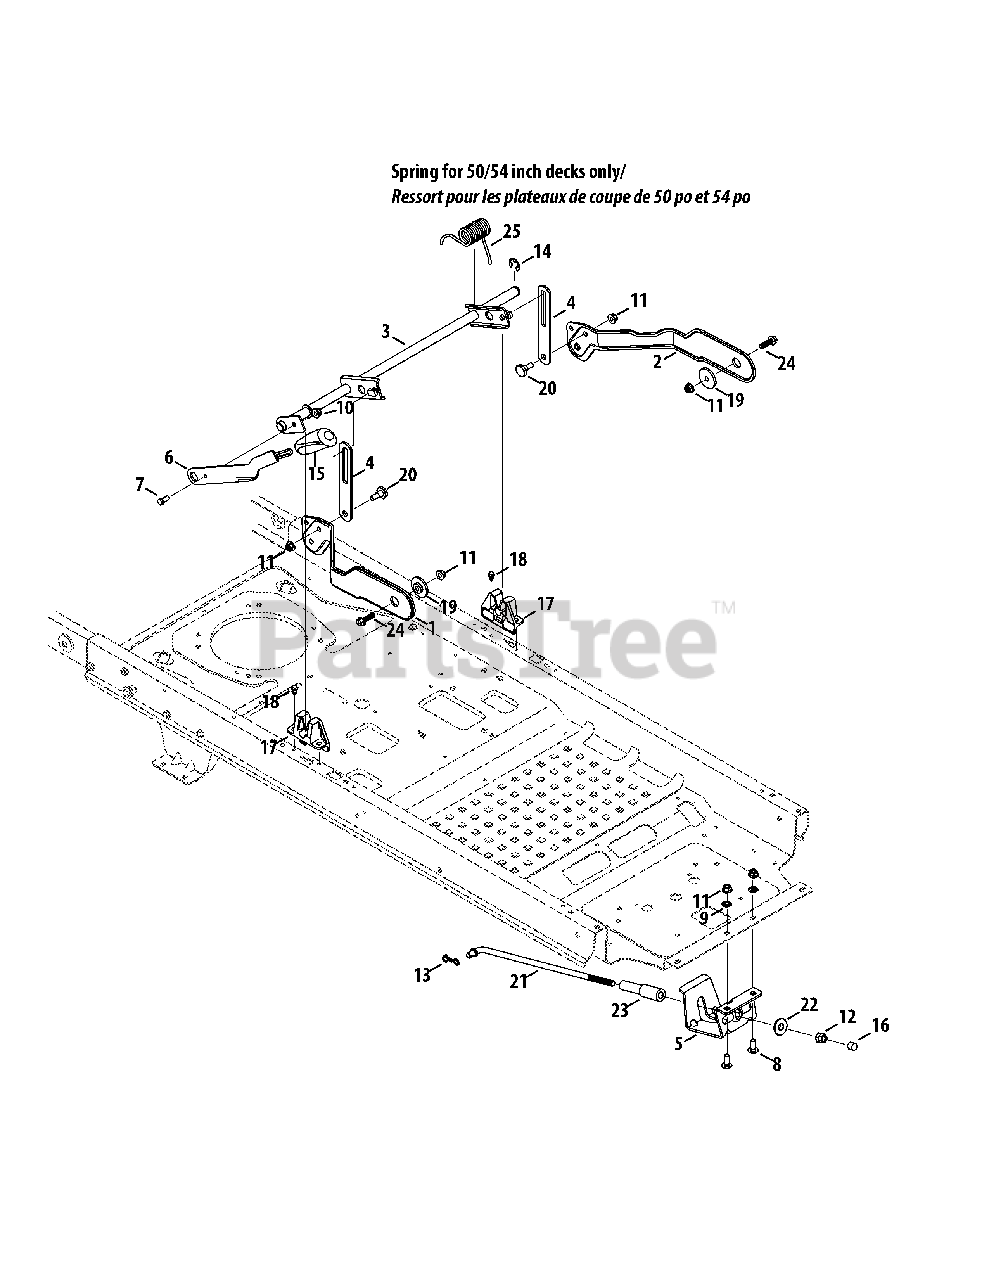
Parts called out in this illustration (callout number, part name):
1	Deck Lift Plate, RH
2	Deck Lift Plate, LH
3	Deck Lift Shift Assembly
4	Lift Link Plate
5	Rod Support Mounting Bracket
6	Deck Lift Handle
7	Hex Cap Screw 5/16-18 x .75
8	Carriage Bolt 3/8-16 x 1.00
9	Push Nut 3/8
10	Flange Lock Nut 5/16-18
11	Flange Lock Nut 3/8-16
12	Hex Nut 1/2-13
13	Bow-Tie Cotter Pin
14	E-Type Ring .750
15	Grip .50 ID
16	End Cap
17	Deck Lift Bracket
18	Shoulder Screw .500 x 1/4-20
19	Shoulder Spacer .854 x .232
20	Shoulder Screw .500 Dia. x .434
21	Deck Lift Rod
22	Deck Lift pivot Cup
23	Nylon Sleeve .55 ID x 4.50 LG
24	Screw, 3/8-16 x 1.00
25	Torsion Spring 1.323 ID x 2.83 Lg.
